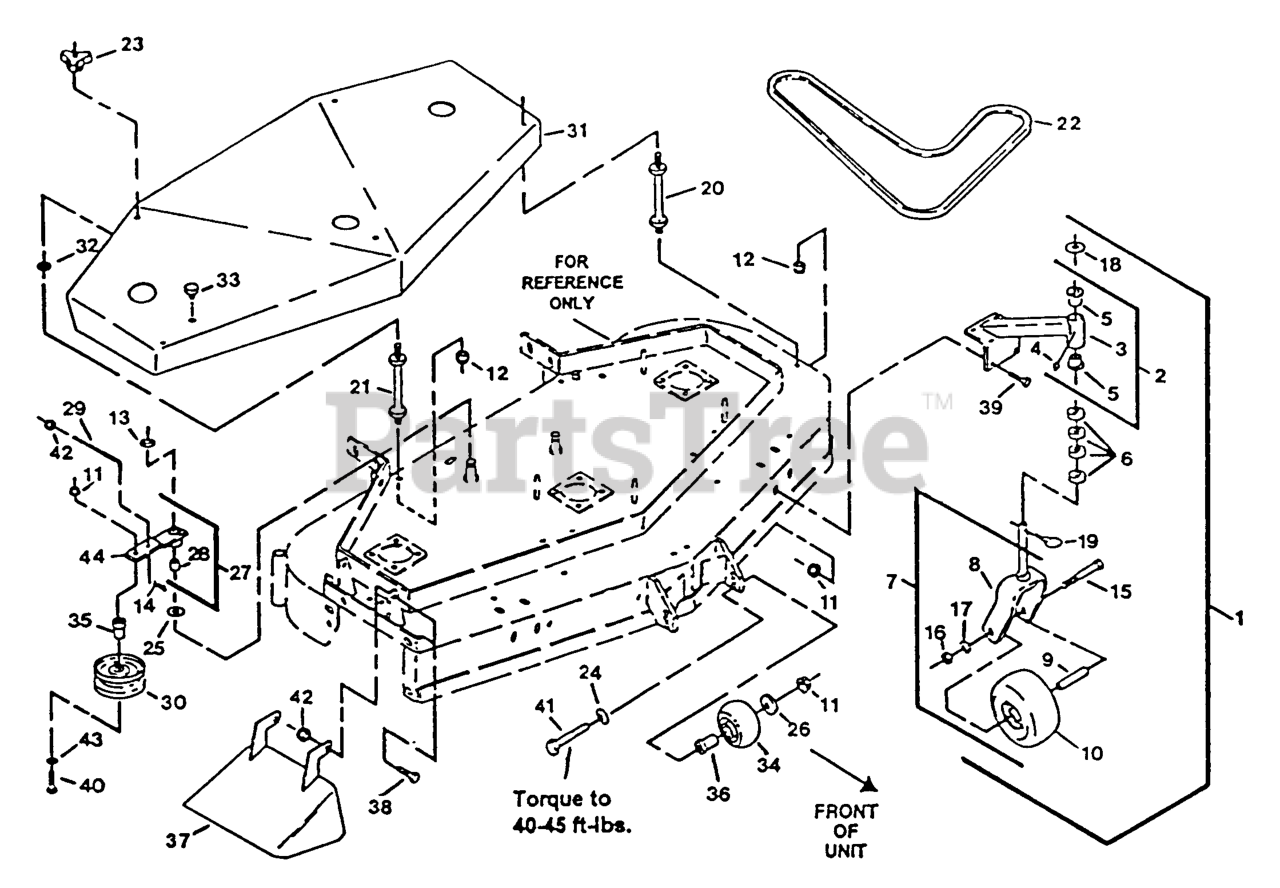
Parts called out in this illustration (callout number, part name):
1	CASTER/MOUNT ASM
2	SUPPORT ASM
5	BEARING-FLANGED
6	SPACER-CASTER
14	PIN-COTTER
18	WASHER-FLAT
20	STUD-SHIELD, BELT (SHORT)
21	STUD-SHIELD, BELT (LONG)
22	BELT,BLADE DRIVE 48
23	KNOB-3 PRONG
25	WASHER-SPINDLE
27	ARM WLDMNT W/BUSHING
28	BEARING,POWDERED METAL
29	LINKAGE
30	IDLER,PULLEY
31	SHIELD,BELT W/DECAL 52
34	ROLLER-SCALP, ANTI
35	BUSHING-IDLER
36	BUSHING-ROLLER
37	WLD,CHUTE DISCHARGE
44	Arm Weldment
